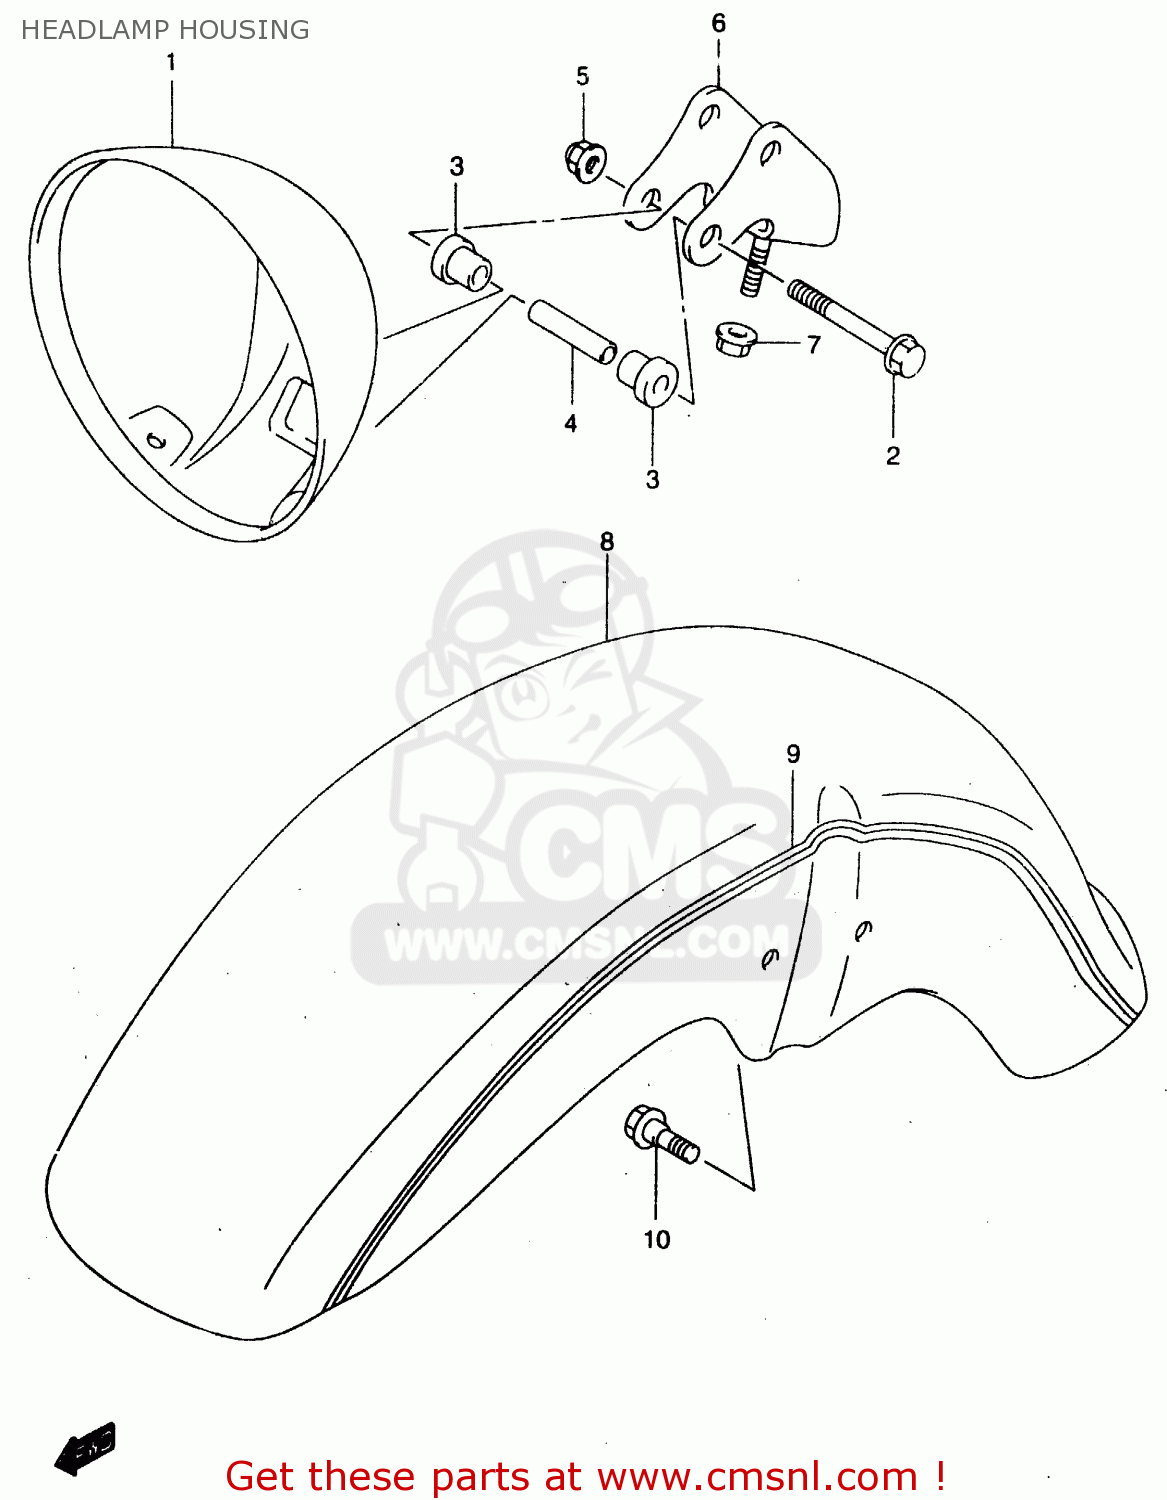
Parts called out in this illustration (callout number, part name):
1	HOUSING,HEADLAMP
2	BOLT
3	CUSHION,HEADLAMP HOUSING
4	SPACER(6.5X9X38.3)
5	NUT
6	BRACKET COMP,HEADLAMP
7	NUT
8	FENDER COMP,FRONT
9	TAPE SET,FR FENDER
10	BOLT(6X16)
